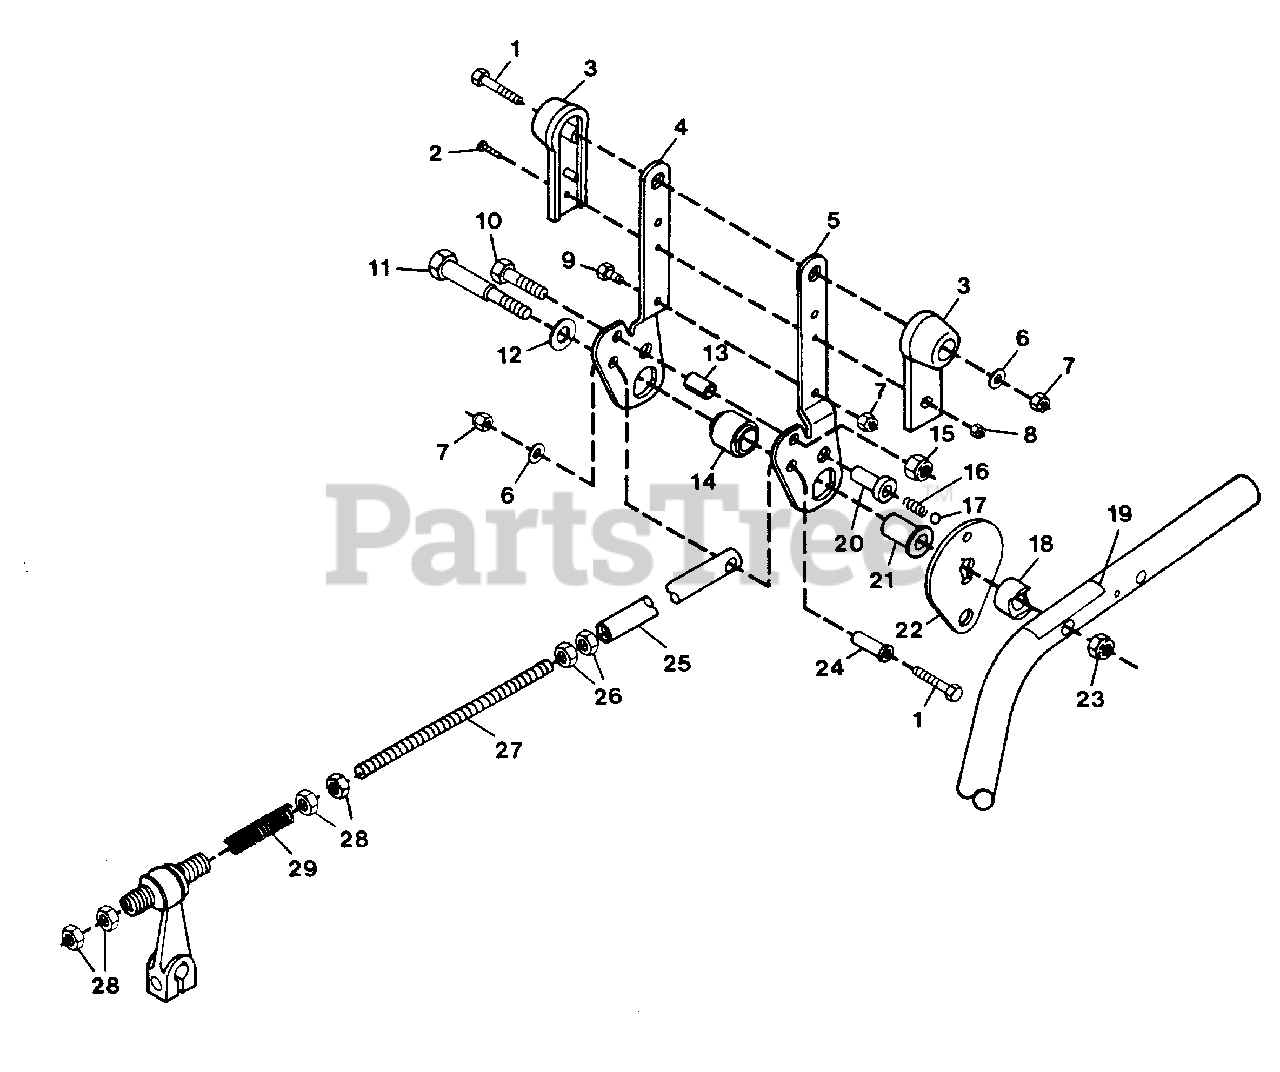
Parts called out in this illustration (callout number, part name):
1	HANDLE, RUBBER SHIFTER
2	ROD, SHIFTER
3	SPRING, EXTENSION .50X1.25
4	NUT, LOCK 3/8-16
5	WASHER, FLAT .406X.812X.065
6	NUT, LOCK 1/4-20
7	WASHER, FLAT .281X.625X.065
8	CAM, SHIFTER
9	BOLT, HEX 1/4-20X1.00
10	SPRING, COMP. .720X2.75
11	BOLT, HEX 1/4-20X1.50
12	BLOCK, SHIFT LEVER
13	LINK, SHIFTER STOP
14	WASHER, SPRING .375 I.D.
15	PIN, COTTER .125X.750
16	WELDMENT, PTO BELLCRANK
17	LINK, PTO CONTROL
18	PIN, COTTER .09X.75
